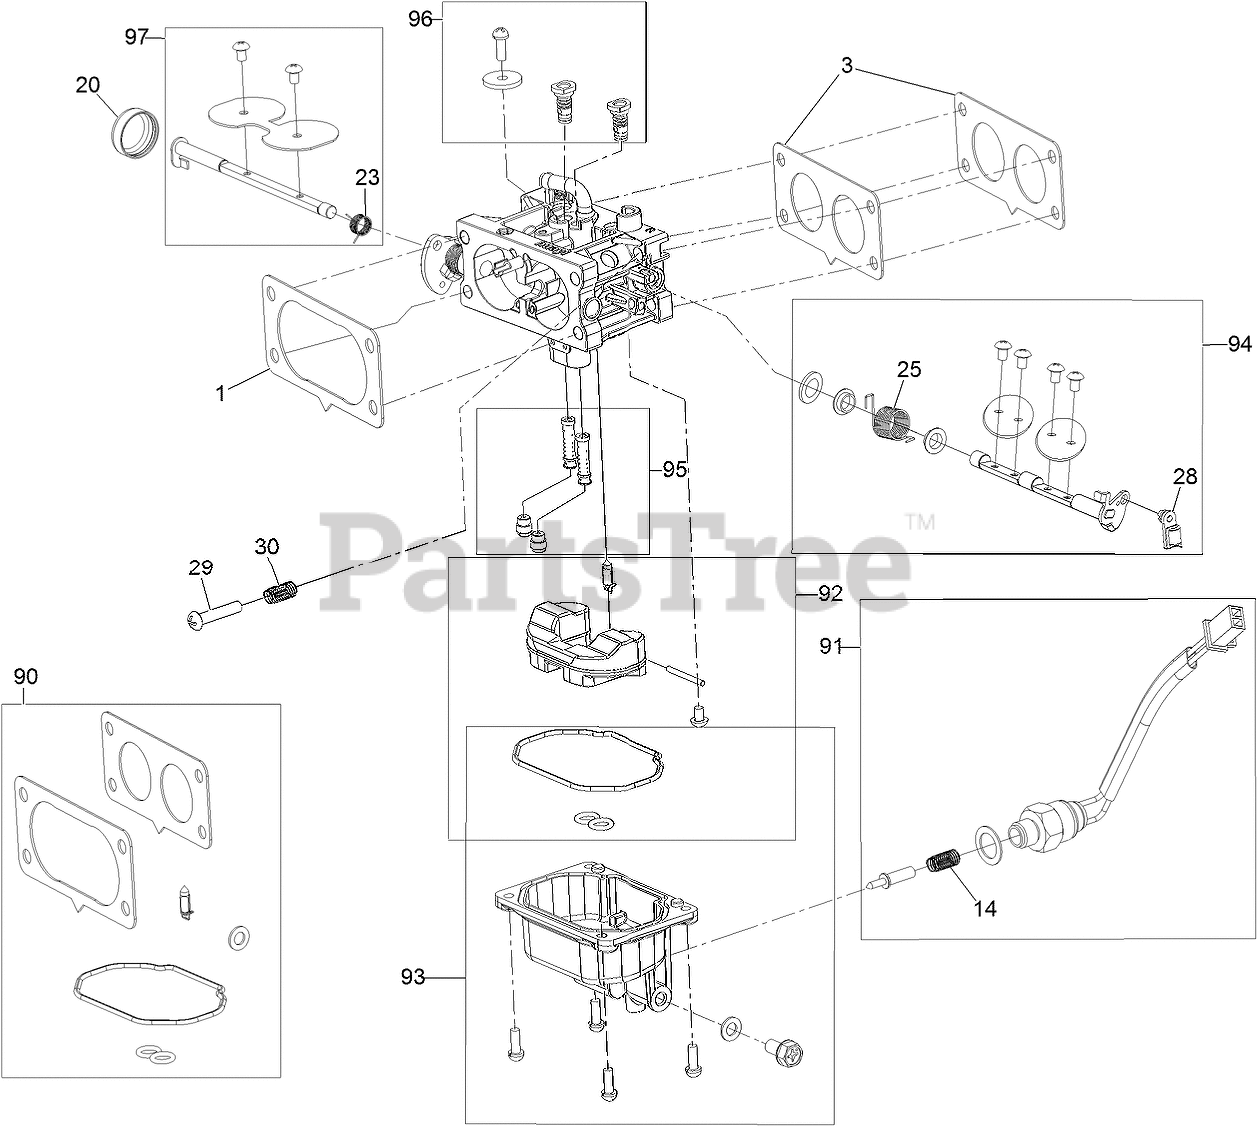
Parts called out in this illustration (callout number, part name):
1	GASKET-CARBURETOR
3	GASKET-CARBURETOR
20	COVER-SHAFT, CHOKE
28	CLAMP-LOCK
29	SCREW-PPH
90	CARBURETOR REPAIR KIT
91	SOLENOID KIT
92	FLOAT KIT
93	BOWL KIT
94	THROTTLE SHAFT KIT
95	NOZZLE AND JET KIT
96	IDLE JET KIT
97	CHOKE SHAFT KIT
